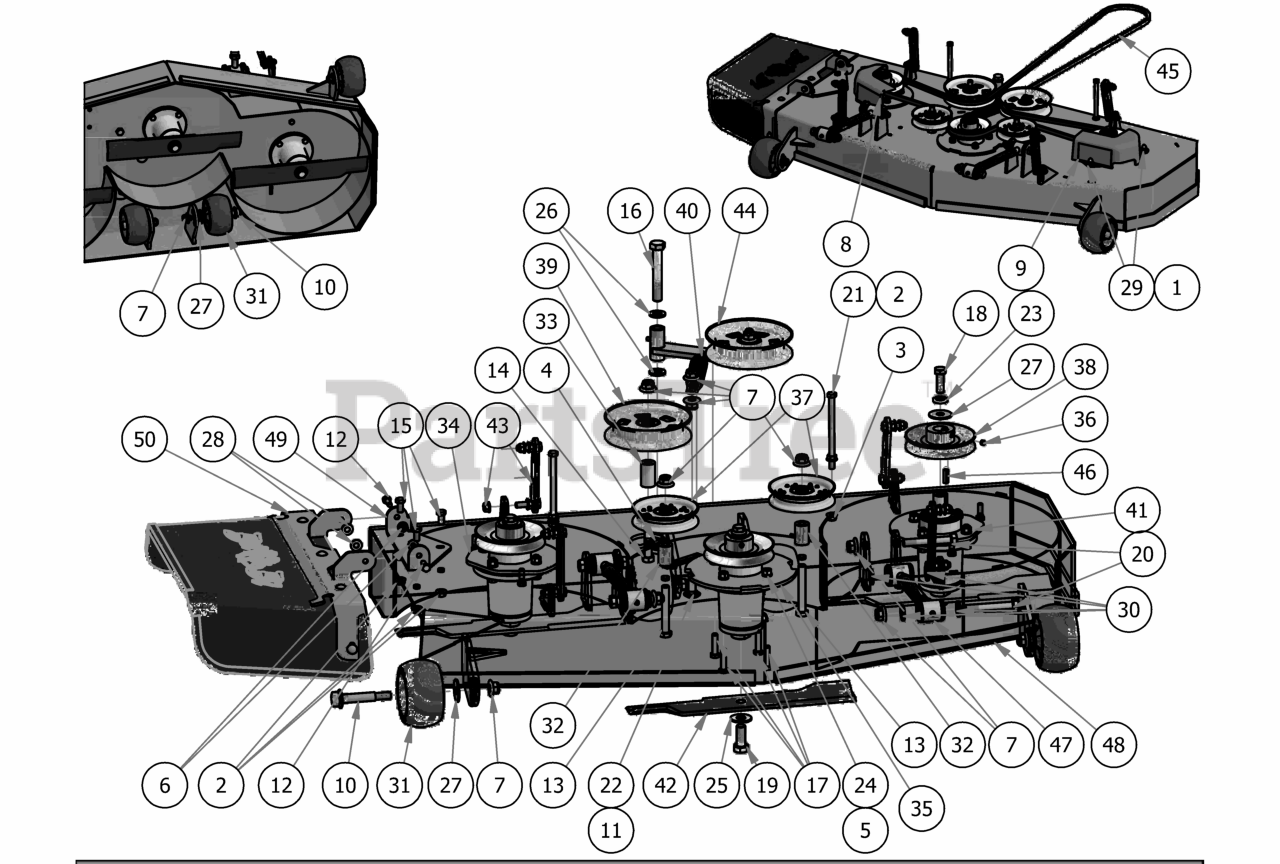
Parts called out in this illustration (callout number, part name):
1	Acorn nut-pulley Cover
2	3/8" Flange Nut
3	3/8" Nylock Flange Nut
4	5/8-11 Nylon Insert Jam Half Nut
5	3/8" Hex Nut
6	5/16" Nylon Flange Nut
7	1/2-13 Nylon Flange Nut
8	pulley cover chute side
9	pulley cover non-chute side
10	Deck Wheel Bolt
11	1/2 x 2" Carriage Bolt
12	5/16-18 x 1 GR 5 Hex Bolt Zinc
13	1/2 x 3 1/2 Flange Bolt Grade 8
14	1/2" x 4" Bolt (Grade 8)
15	3/8" x 3/4" Hex Bolt
16	5/8" x 4" Hex Bolt
17	3/8 x 1.5" Bolt
18	1/2"-20 x 1 1/2 - Grade 5 Fine Thread Bolt
19	5/8 x 1 1/2 Grade 8 Hex Bolt (Fine)
20	1/2-13 x 3 1/2 GR 5 Hex Bolt
21	3/8-16 x 5 1/2 Hex Bolt
22	.517 Square Hole Round Washer
23	1/2" Lock Washer Zinc
24	3/8" Lock Washer
25	5/8'' Flat Washer
26	.630 ID Plastic Washer
27	1/2" Belleville Washer
28	.360 ID Plastic Washer
29	.360 ID Plastic Washer-Black
30	.505 Nylon Spacer
31	Deck Wheel
32	Idler Pulley Standoff
33	1 3/4" Pulley Spacer
34	42&48 Deck Spindle Support Plate
35	Deck Spindle Support Plate
36	5/16 Set Screw
37	4 3/4 Idler Pulley - ABFI-76
38	5" Spindle Deck Pulley
39	5-3/4 Idler Pulley
40	Deck Idler Spring
41	Spindle Assembly
42	16 1/4" Bad Boy Blade
43	Deck Hanger Assembly
44	2017 54"/48" Deck Idler Assembly
45	B147 Deck Belt
46	1/4" x 1" Key
47	2018 Maverick Turnbuckle (Top Link)
48	2017 48" ZT Deck
49	Discharge Chute Hanger (deck mounted)
50	ZT Chute Assembly
